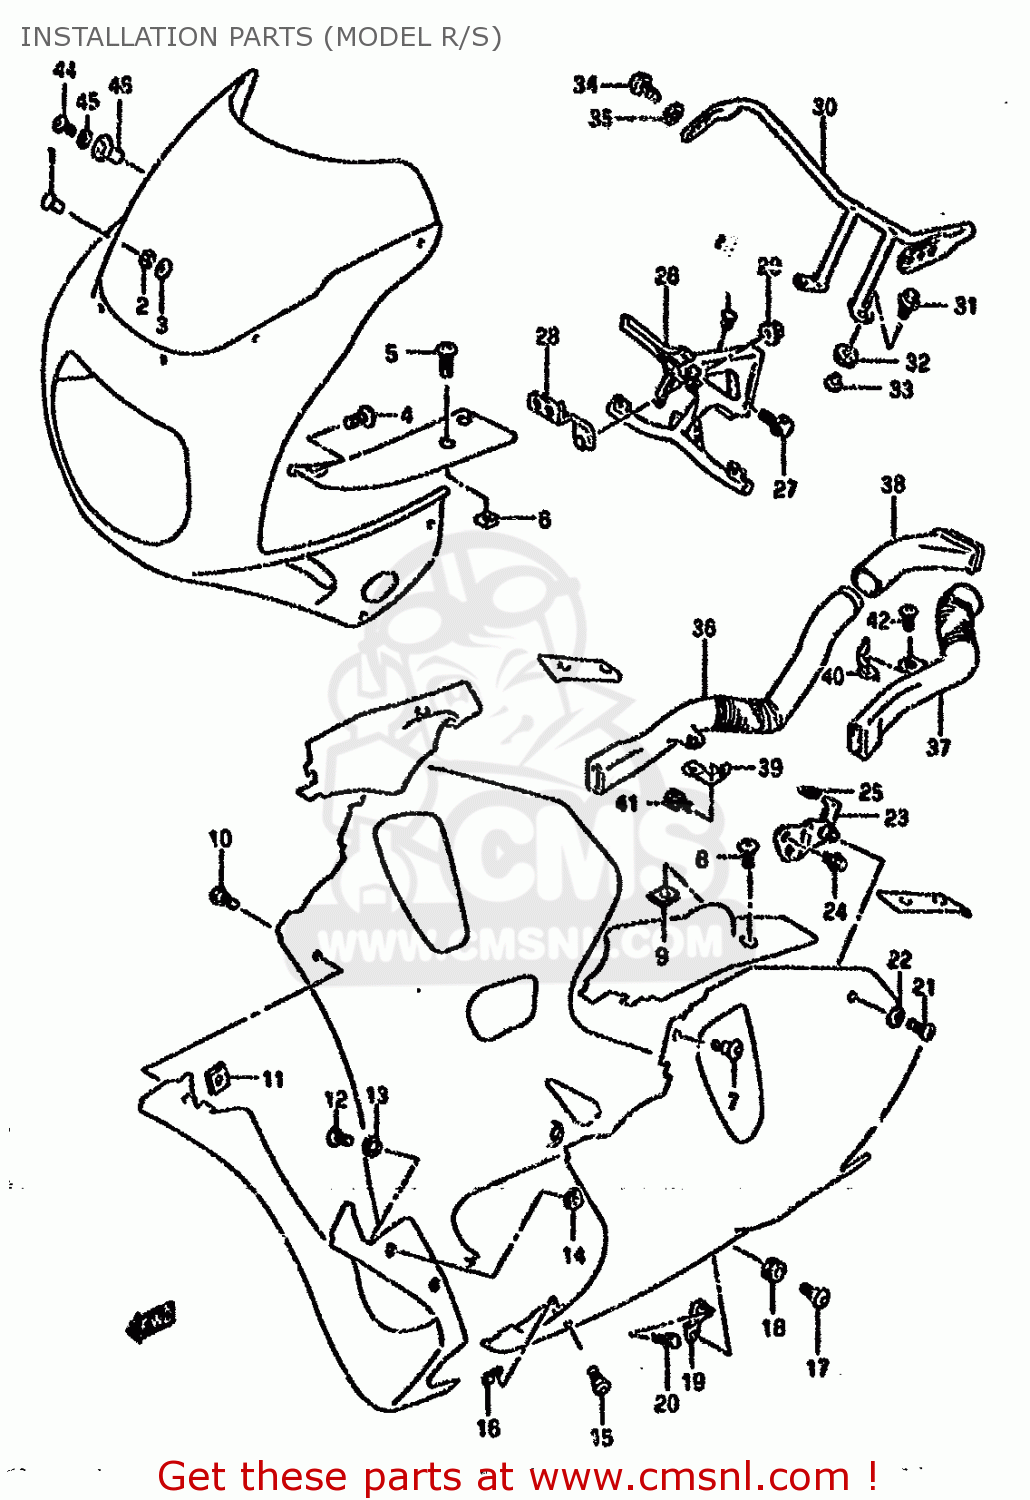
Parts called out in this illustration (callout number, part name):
1	PIN,WINDSCREEN
2	CUSHION
3	NUT
4	SCREW 5X10
5	SCREW L:12
6	NUT
7	SCREW(5X16)
8	SCREW L:12
9	NUT
10	SCREW(5X16)
11	NUT,RH & CTR UNDER COWLING
12	SCREW
13	WASHER(5.2X14X1.5)
14	NUT
15	SCREW(5X16)
16	NUT,RH & CTR UNDER COWLING
17	SCREW(6X20)
18	CUSHION
19	BRACKET,UNDER COWLING LWR,R
20	BOLT
21	SCREW(6X10)
22	WASHER
23	BRACKET,UNDER COWLING,UPPER
24	BOLT
25	NUT
26	BRACE,COWLING
27	BOLT
28	BRACKET,HEADLAMP
29	NUT
30	BRACE,RR VIEW MIRRORR
31	BOLT(6X25)
32	CUSHION
33	WASHER
34	SCREW(6X12)
35	WASHER(6.2X19X1.5)
36	PIPE,AIR INTAKE FR,R
37	PIPE,AIR INTAKE FR,L
38	PIPE,AIR INTAKE,REAR,RIGHT
39	BRACKET,AIR INTAKE,RIGHT
40	BRACKET,AIR INTAKE,LEFT
41	BOLT
42	SCREW 6X12
43	CAP(OD:14)
44	SCREW(5X14)
45	WASHER
46	NUT
